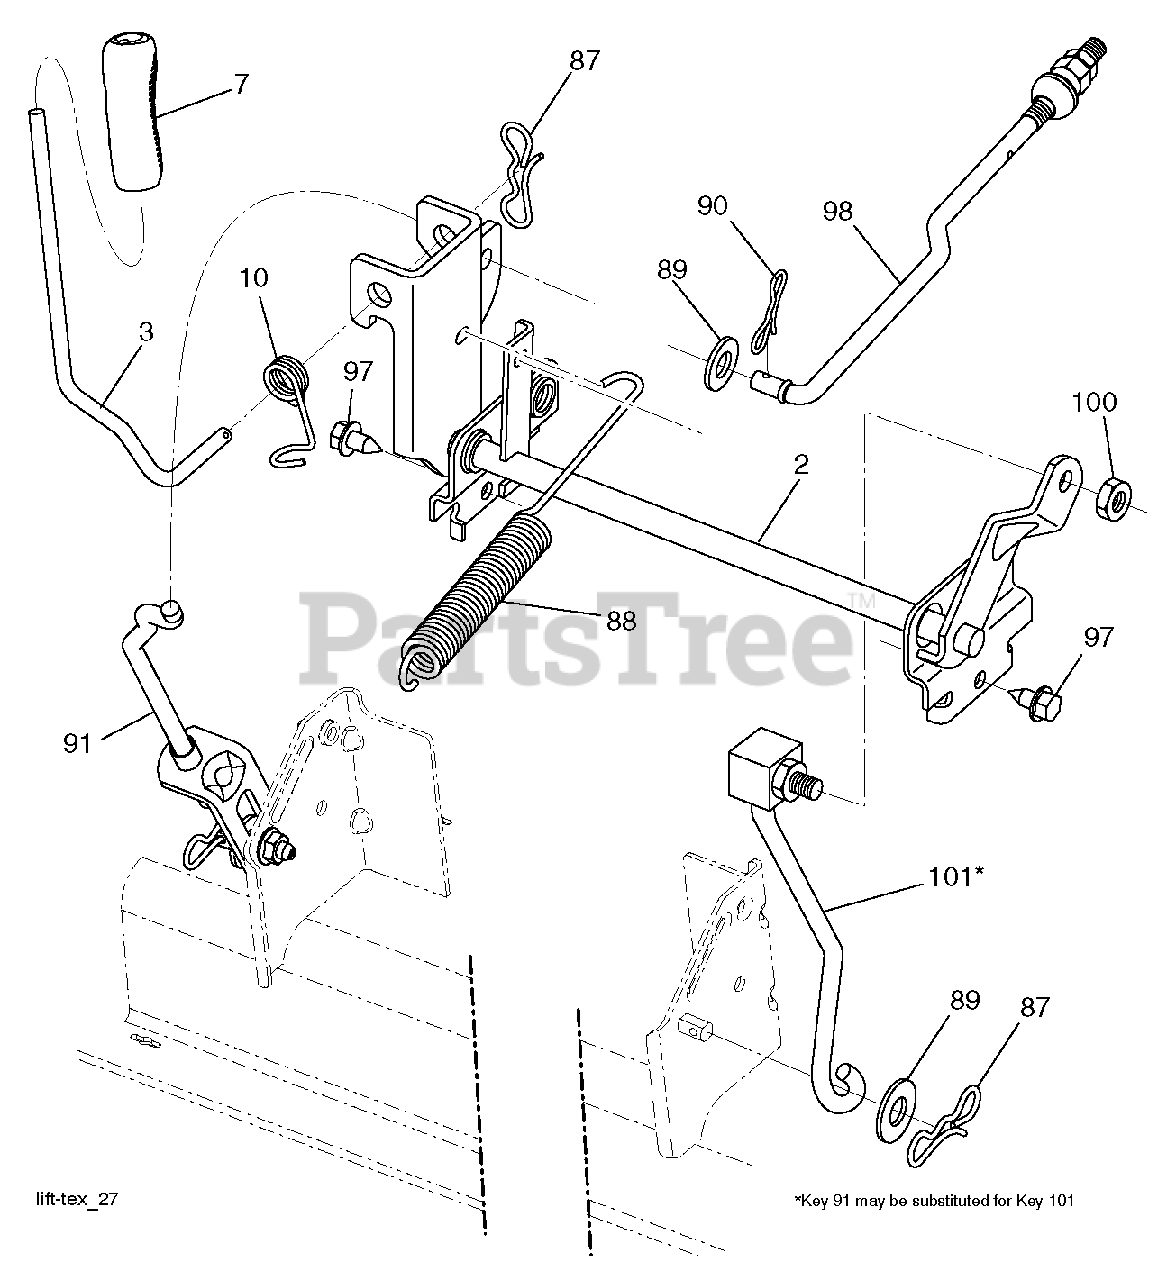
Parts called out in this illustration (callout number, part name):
2	SHAFT LIFT DECK WELD
3	LEVER.LIFT.HANDLE.LT
7	GRIP.HANDLE.LIFT.PVC.BLACK
10	SPRING.TORSION.LIFT.HANDLE
87	PIN.COTTER.7/16.BOW TI.
88	SPRING SPRING LIFT ASSIST 97
89	WASHER.CLEAR.ZINC
90	PIN.COTTER.5/16.BOW TI
91	LINK.ASM.LIFT.REAR
97	SCREW LT
98	LINK.ASM.SUSP.FRONT.MW
100	LOCKNUT
101	LINK.ASM.LIFT.FIXE.38/42/46"
